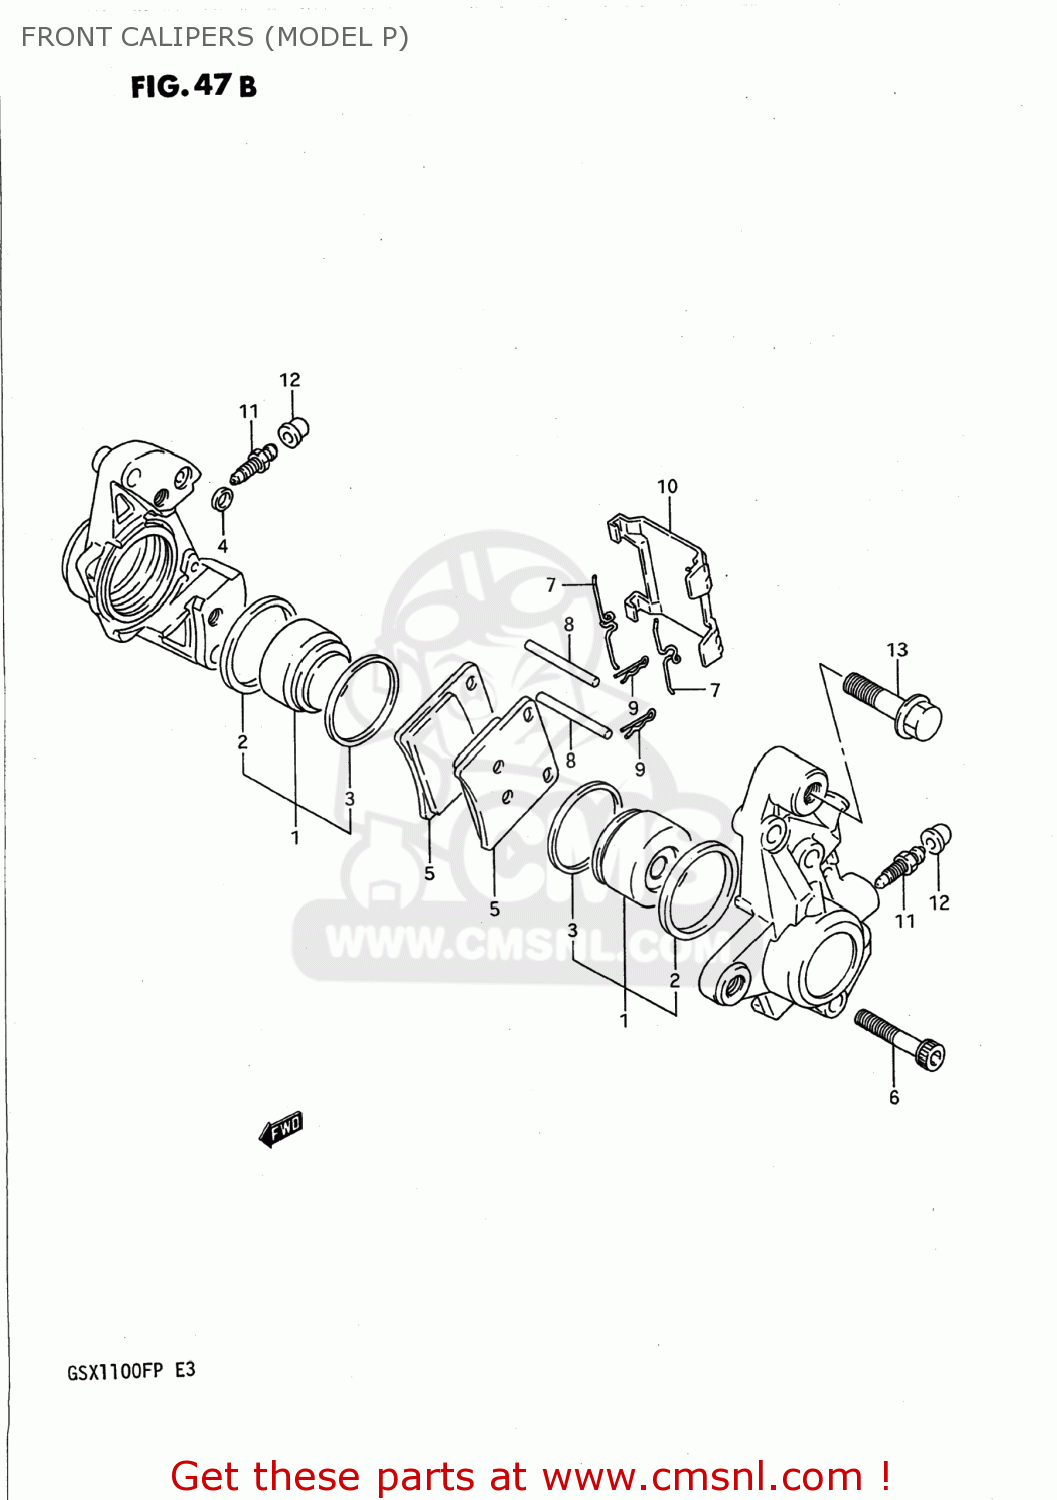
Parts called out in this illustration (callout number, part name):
1	PISTON SET
2	SEAL,PISTON
3	SEAL,WIPER
4	SEAL,JOINT
5	PAD
6	BOLT,CALIPER
7	SPRING
8	PIN,PAD
9	CLIP,PAD PIN
10	COVER,CALIPER
11	BLEEDER
12	CAP,BREATHER
13	BOLT
